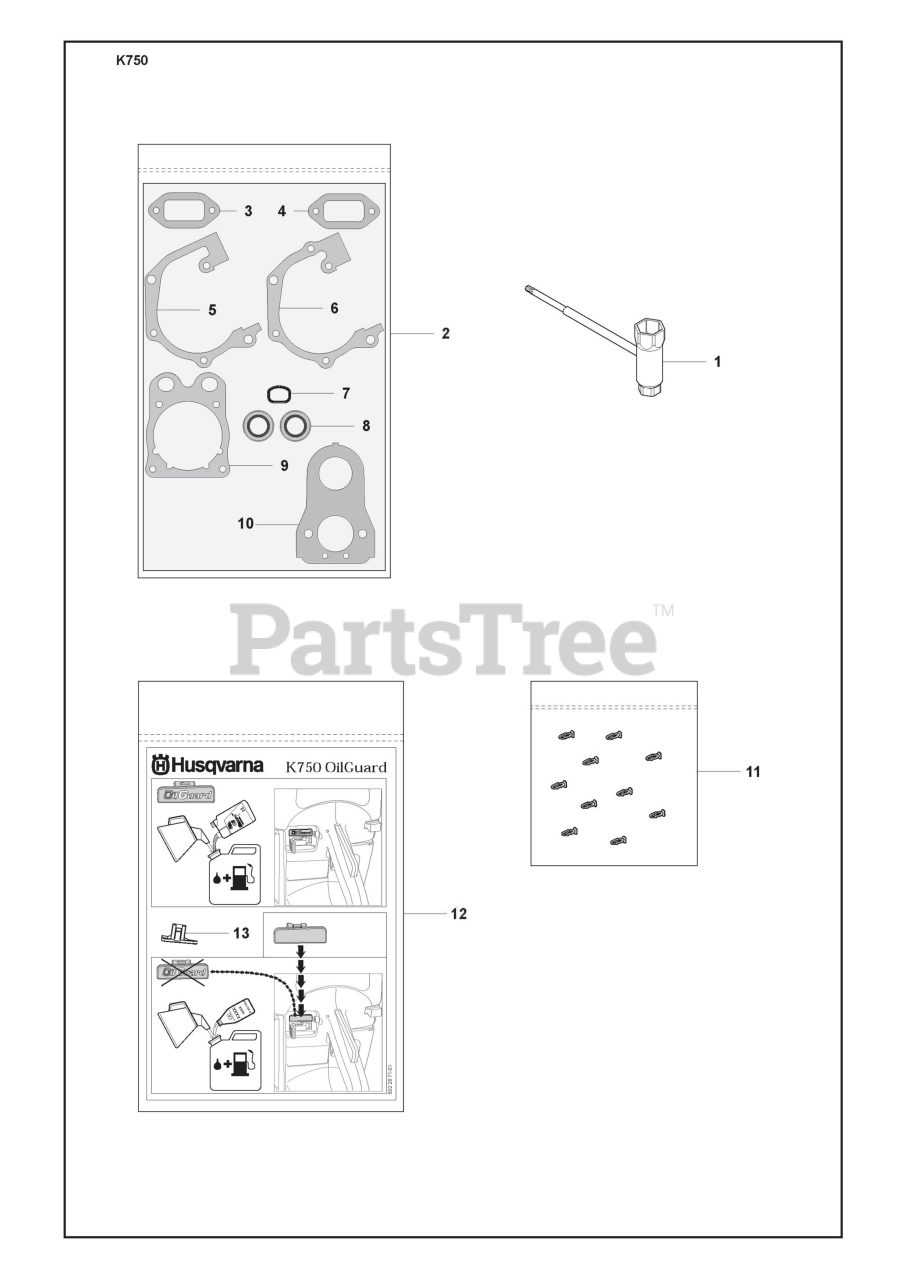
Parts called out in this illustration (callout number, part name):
1	COMBINATION TOOL
2	GASKET KIT
4	GASKET MUFFLER
5	GASKET CRANKCASE
6	GASKET CRANKCASE
8	SEALING RING
9	CYLINDER BASE GASKET
10	GASKET CARBURETTOR
11	KIT BREAK PIN
12	KIT SWITCH OFF
